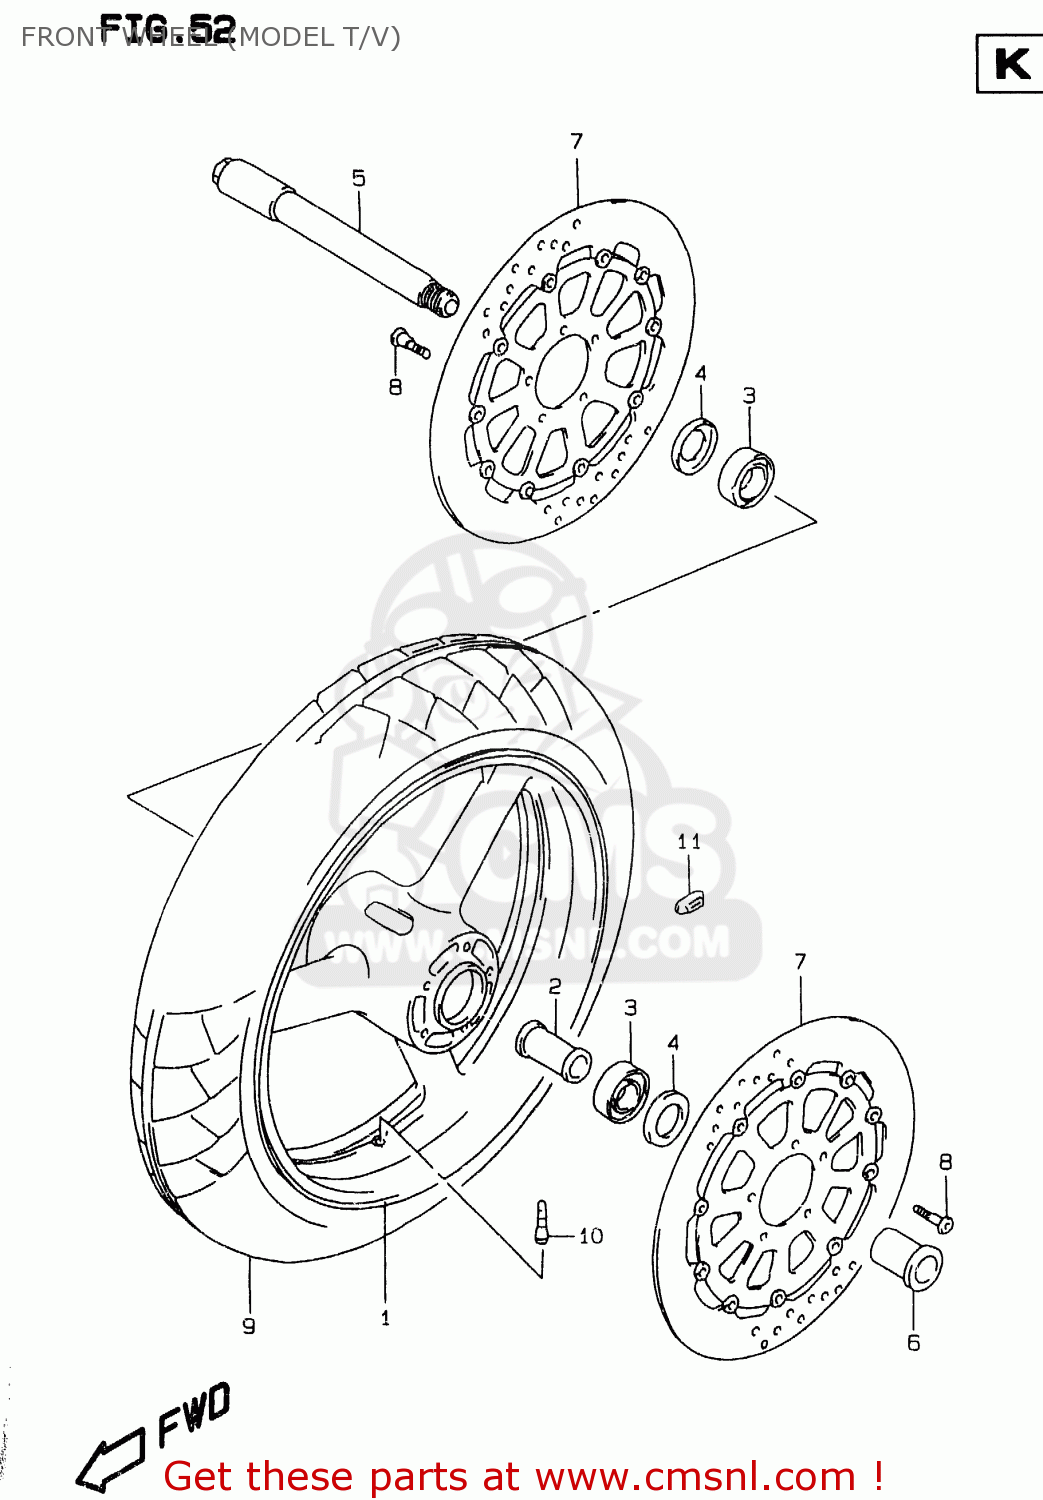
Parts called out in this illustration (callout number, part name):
1	WHEEL,FRONT (17XMT3.50)(
2	SPACER,FRONT HUB BEARING
3	BEARING(25X52X15)
4	SEAL,OIL(32X52X7)
5	AXLE,FR
6	NUT,FR AXLE
7	DISC,FR BRAKE
8	BOLT 8X33
9	TIRE,FRONT 120/70 ZR17
10	VALVE ASSEMBLY,WHEEL,TR412
11	BALANCER,WHEEL (10G)
